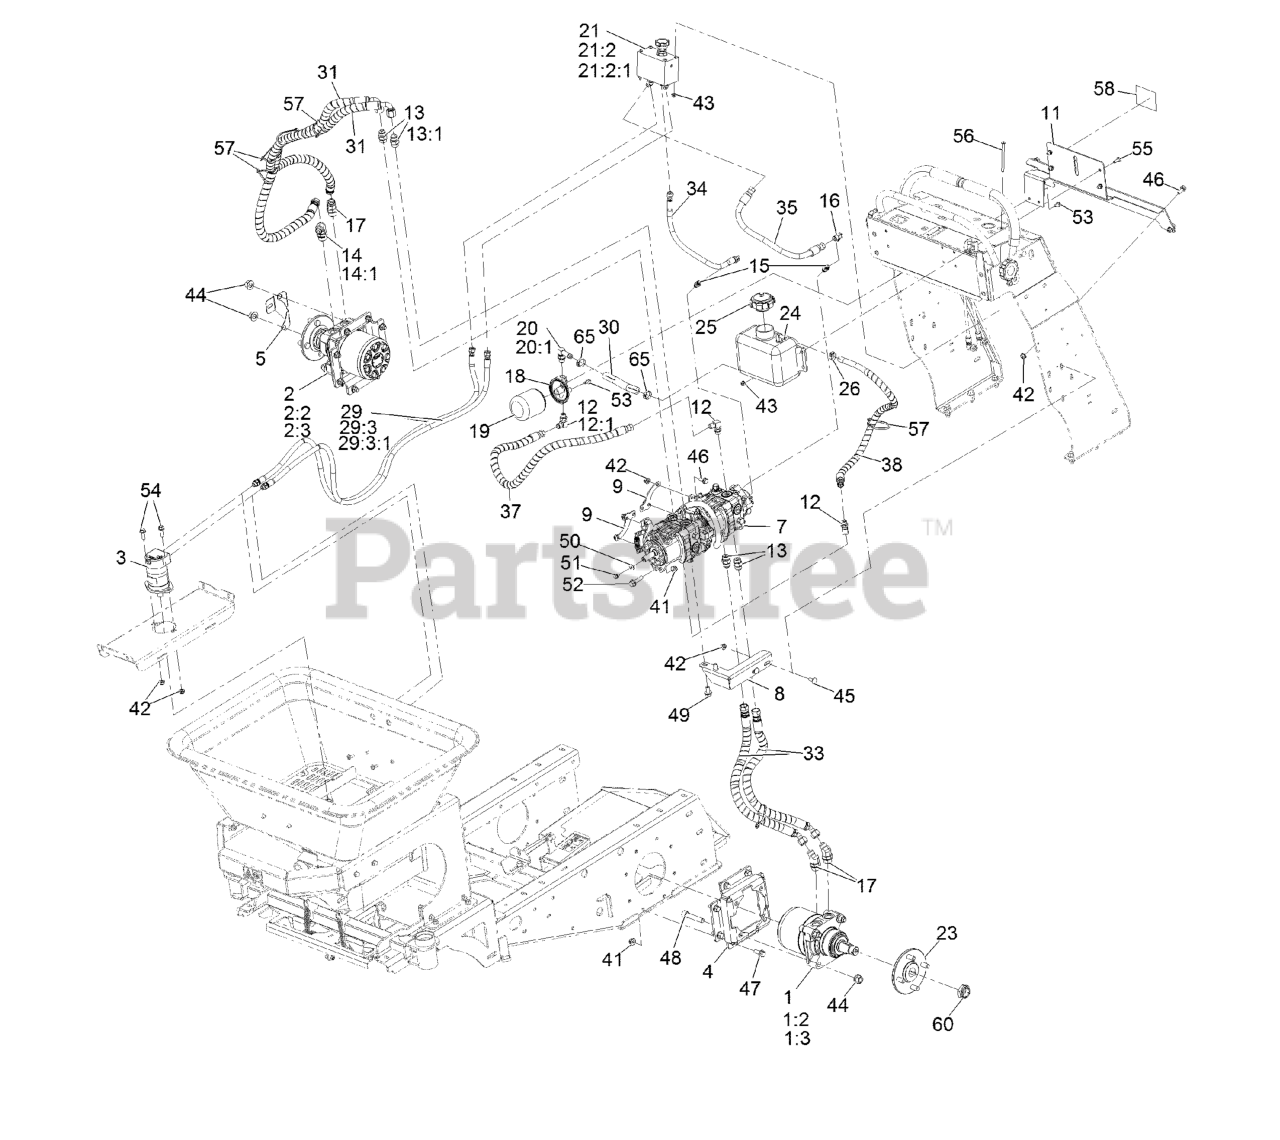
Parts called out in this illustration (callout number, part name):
1	MOTOR, LH WHEEL
1:2	KEY-WOODRUFF
1:3	SEAL KIT
2	MOTOR, RH WHEEL
2:2	KEY-WOODRUFF
2:3	SEAL KIT
3	MOTOR-HYDRAULIC, SPREADER
4	Mount-Motor, Wheel
5	BRACKET-HOPPER, SPEEDOMET
7	PUMP-TANDEM
8	Bracket-Support, Hydro Pump
9	Extension, Hydro Pump
11	Mount, Hydraulic Tank And Filter
12	FITTING-ELBOW, 90 DEG
12:1	O-RING
13	FITTING-STRAIGHT
13:1	O-RING
14	FITTING-90 DEG
14:1	O-RING
15	FITTING-STRAIGHT
16	FITTING-90 SWIVEL
17	FITTING-ELBOW, 45 DEG
18	HEAD-FILTER
19	FILTER-HYDRAULIC
20	FITTING-ELBOW, 90
20:1	O-RING
21	MANIFOLD-HOPPER, W/OUT RE
21:2	FITTING-ELBOW, 45 DEG
21:2:1	O-RING
23	HUB-WHEEL
24	TANK-HYDRAULIC, PLASTIC
25	Cap-Vented
26	CLAMP-OETIKER, 167
29	HOSE ASM, HYD HP
29:3	Fitting-Straight, Rigid
29:3:1	O-RING
30	HOSE-HYDRAULIC
31	HOSE ASM, HYD HP
33	HOSE ASM, HYD HP
34	Hose ASM, HYD HP
35	Hose ASM, HYD LP
37	Hose ASM, HYD LP
38	Hose ASM, HYD LP
41	Nut-Hex Flange
42	Nut-Hex Flange
43	Nut-Hex Flange
44	Nut-Lock 1/2-13
45	SCREW-CARR
46	SCREW-HHF
47	SCREW-HHF
48	Screw-HSH
49	SCREW-HHF
51	SCREW-HHF
52	SCREW-HHF
53	SCREW-HHF
54	SCREW-HHF
55	Screw-Hsbhf
56	Screw-HSBH
57	TIE-CABLE
58	DECAL-OIL
60	LOCKNUT
65	CLAMP-OETIKER, 167
